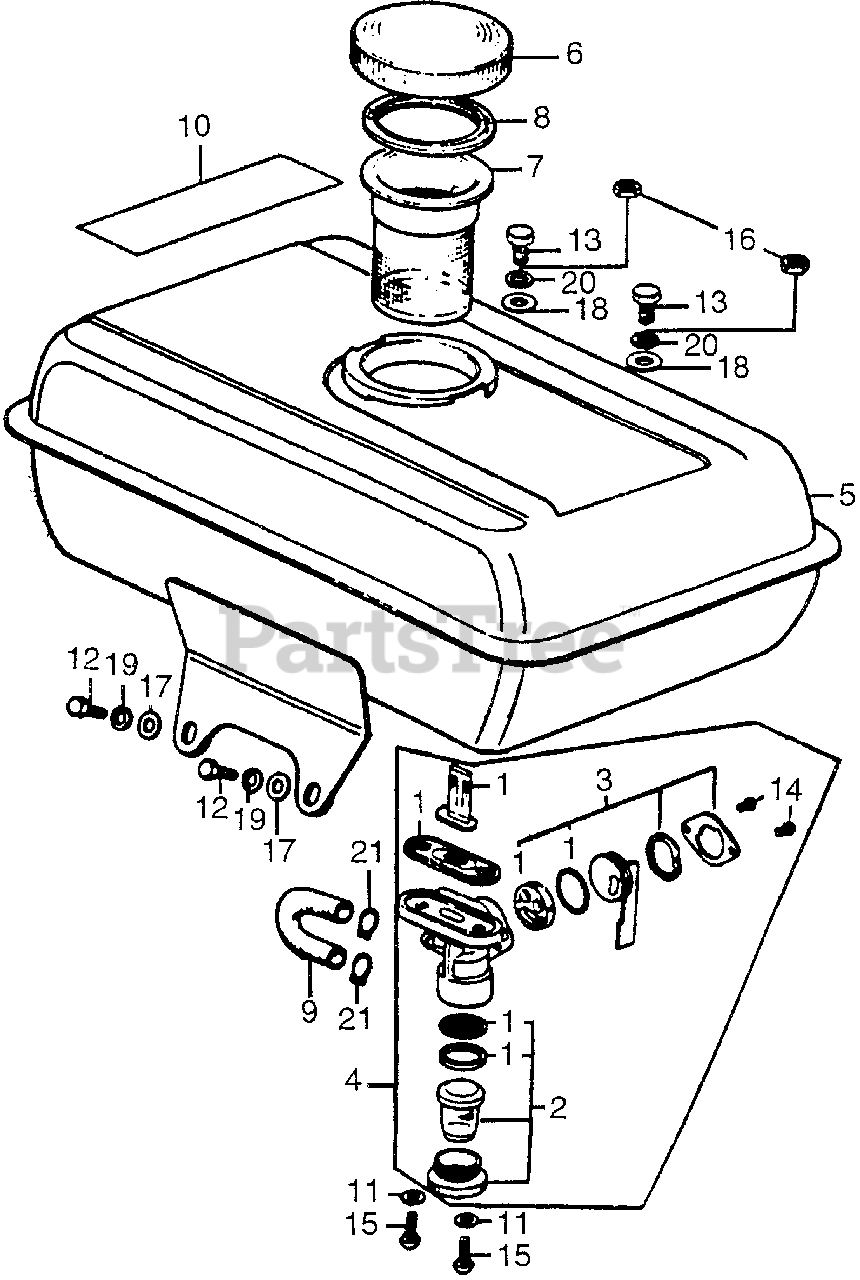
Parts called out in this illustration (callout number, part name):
1	GASKET SET, VALVE
2	CUP SET, STRAINER
3	LEVER SET, VALVE (NOT AVAILABLE)
4	PETCOCK ASSY.
5	TANK, FUEL *NH31* (MCKINLEY WHITE) (NOT AVAILABLE)
6	CAP, FUEL TANK (NOT AVAILABLE)
7	FILTER, FUEL
8	GASKET, FUEL FILTER (NOT AVAILABLE)
9	TUBE, FUEL (NOT AVAILABLE)
10	MARK A, CAUTION
11	GASKET, FIBER (6MM)
12	BOLT, HEX. (6X16)
13	BOLT, HEX. (8X20)
14	SCREW, PAN (3X8)
15	SCREW, PAN (6X16)
16	NUT, HEX. (8MM)
17	WASHER, PLAIN (6MM)
18	WASHER, PLAIN (8MM)
19	WASHER, SPRING (6MM)
20	WASHER, SPRING (8MM)
21	CLIP, TUBE (B10)
